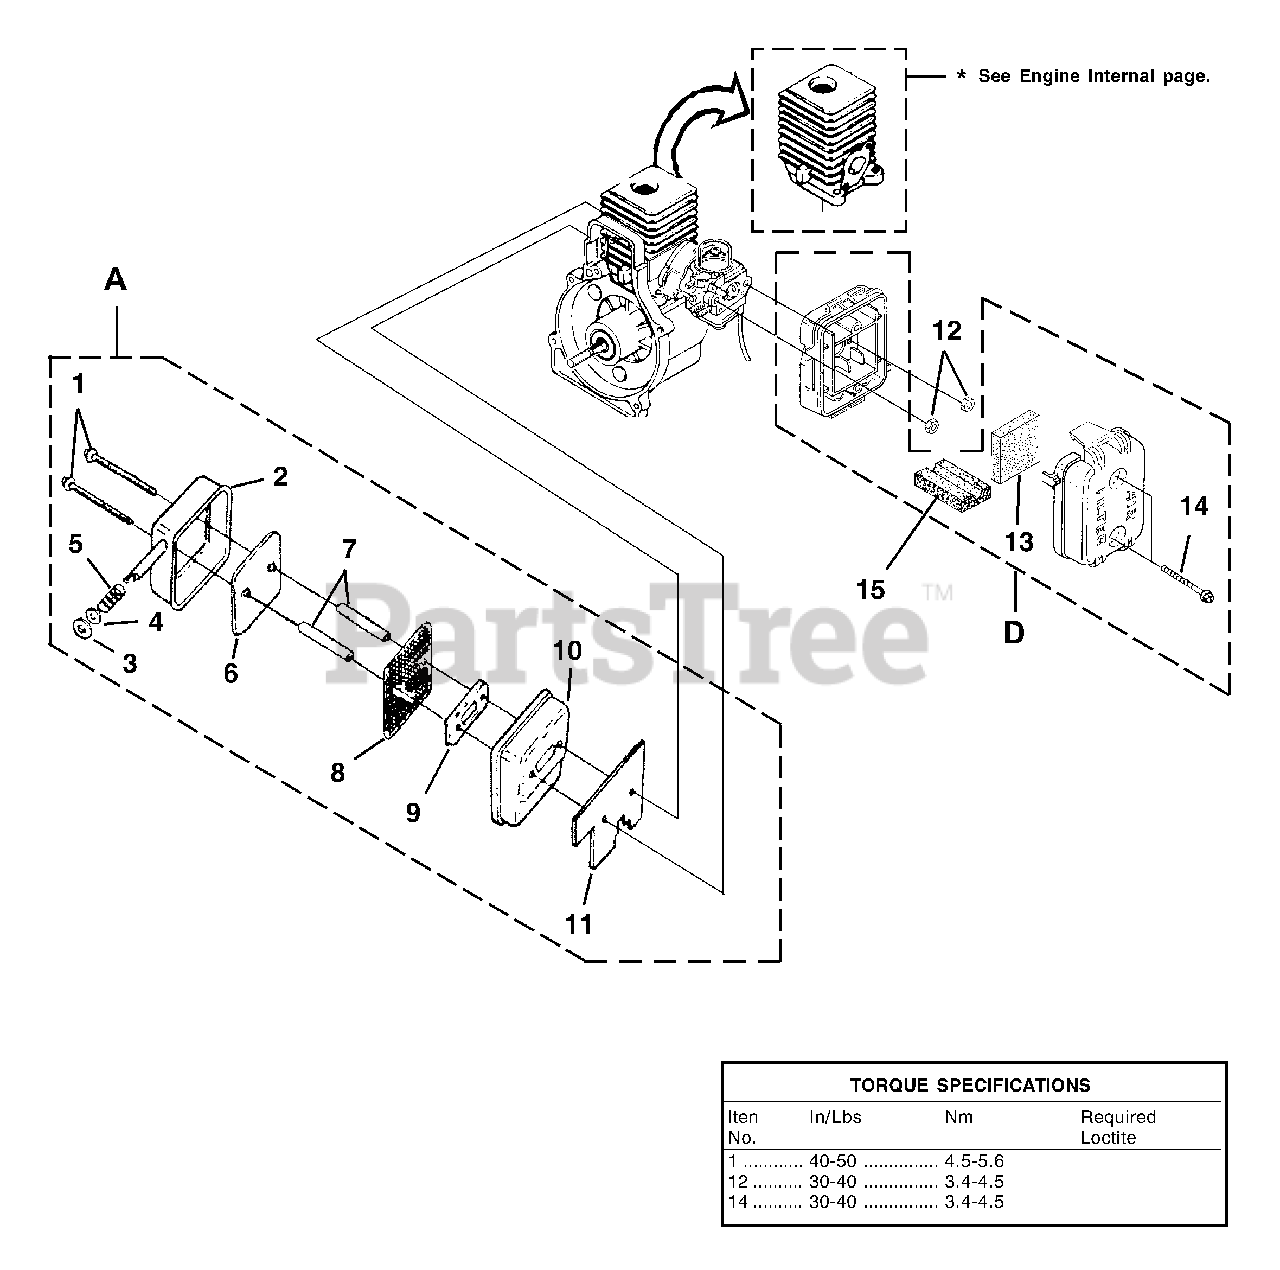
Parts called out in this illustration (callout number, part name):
1	SCREW-Sems Hex Hd. (10-24 x 2 1/2")
2	MUFFLER COVER
3	WASHER-Insulating
4	WASHER-Flat
5	SPRING-Compression
6	DEFLECTOR-Muffler
7	SPACER-Muffler
8	SCREEN-Spark Arrestor
9	PLATE-Reinforcing
10	BODY-Muffler
11	GASKET-Muffler
12	NUT-Hex (10-24)
13	AIR FILTER
14	SCREW-Thd. Form. (#8-16 x 3/4")
15	FOAM AIR FILTER
A	MUFFLER-Complete
D	AIR FILTER KIT
